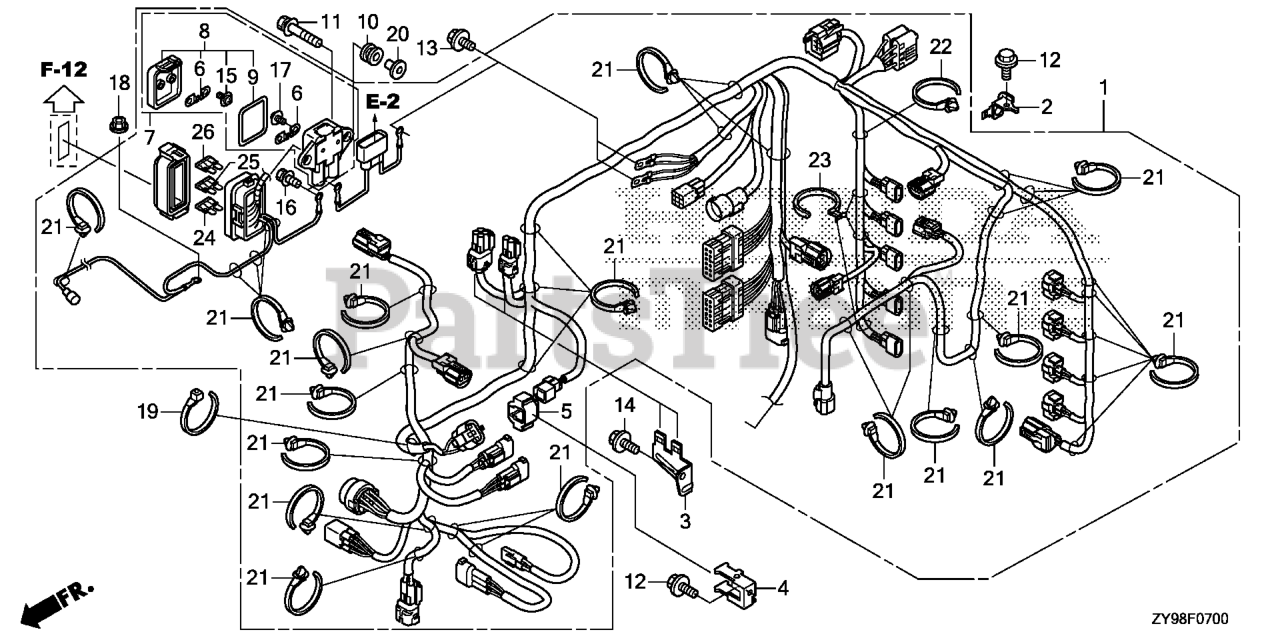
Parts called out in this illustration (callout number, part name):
1	WIRE HARNESS ASSY., MAIN
2	BRACKET A, CONNECTOR
2	BRACKET, CONNECTOR A
3	BRACKET C, CONNECTOR
3	BRACKET, CONNECTOR C
4	BRACKET, CONNECTOR
5	SUSPENSION, CONNECTOR
6	FUSE (70A)
7	BOX ASSY., FUSE (70A)
8	COVER ASSY., FUSE (70A)
9	GASKET, FUSE BOX COVER
10	GROMMET, RELAY
11	BOLT-WASHER (6X27) (CT200)
11	BOLT-WASHER (6X27)
12	BOLT, FLANGE (6X14) (CT200)
13	BOLT, FLANGE (6X12)
14	BOLT, FLANGE (6X10)
15	SCREW-WASHER (3X7)
16	BOLT-WASHER (5X9)
17	SCREW-WASHER (5X10)
18	NUT-WASHER (8MM)
19	BAND, WIRE HARNESS
20	COLLAR, MODULE IGNITION CONTROL CASE (CDI)
20	COLR, CDI UNIT CASE
20	COLLAR (12X6.5)
21	CLIP, HARNESS BAND (145MM) (BLACK)
22	CLIP, HARNESS BAND (151MM) (BROWN)
23	STRAP, HARNESS (30) (107.5MM) (BLACK)
24	FUSE, MINI (10A)
25	FUSE, MINI (15A)
26	FUSE, MINI (30A)
